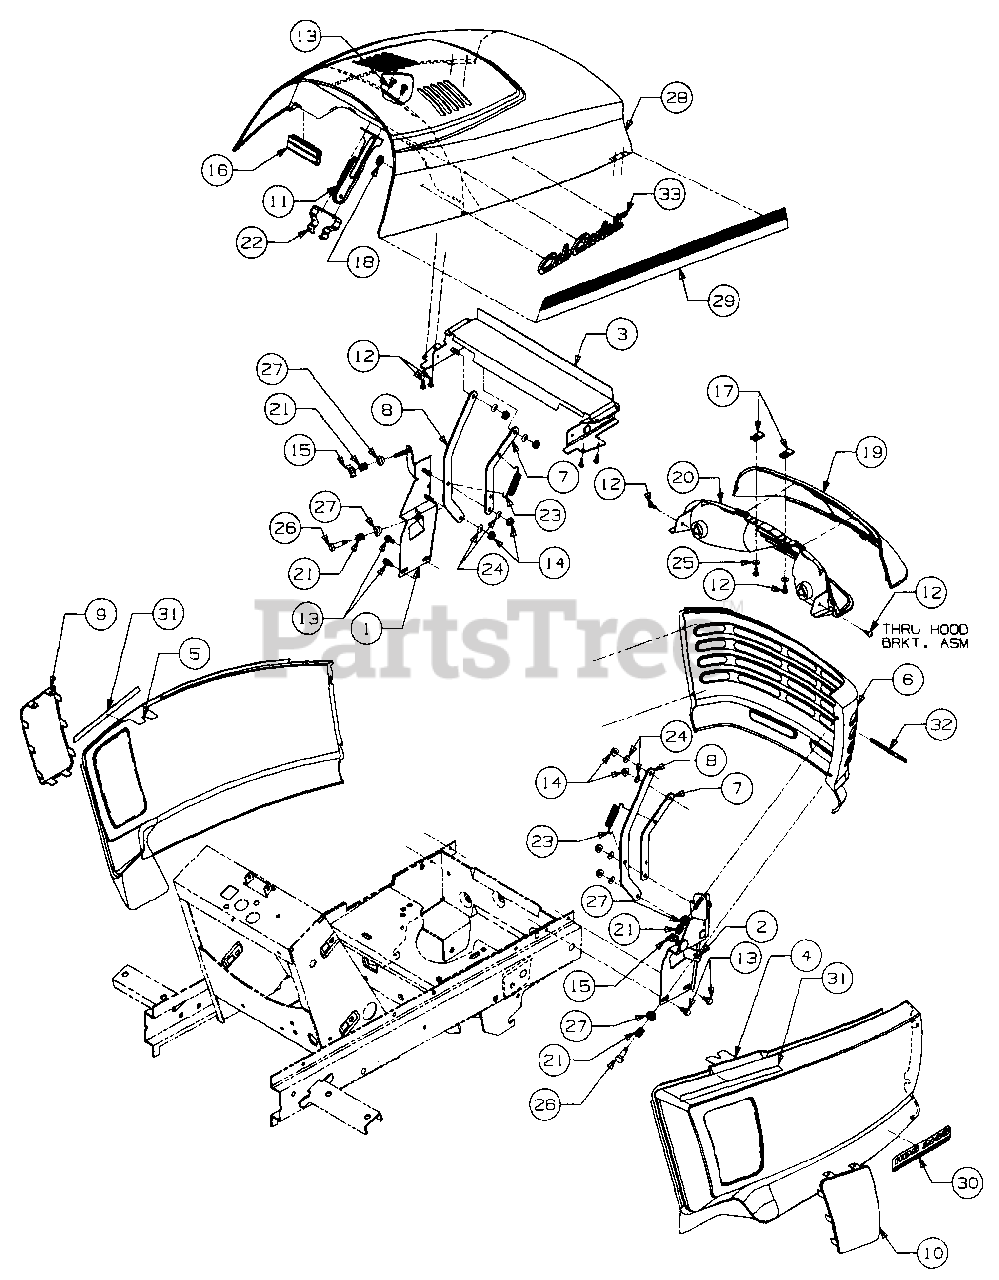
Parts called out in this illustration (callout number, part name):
1	Bracket, Grille LH
2	Bracket, Grille RH
8	Link, Long Hood
12	Screw, Truss Mach Tapp, #10 x .50 Lg
13	Screw, Hex Wash Tapp, 1/4 X .50 Lg
14	Nut, Hex Flange Lock, 1/4-20
15	Nut, Wing, 1/4-20
16	Seal, Heat Baffle
17	Nut, U-Type Speed, #10
18	Retainer, Push Nut
19	Lens, Cub Cadet
20	Reflector, Headlight
21	Spring, Compression, .50 OD X .50 Lg
22	Spring, Hood Latch
23	Spring, Extension, .50 OD x 2.25 Lg
24	Washer, Spring, .265 x .562 x .025 Thk
25	Washer, Flat, .218 X .62 X .063 Thk
26	Bolt, Shoulder .31 Dia X .75 Lg
27	Bushing, Tapered
30	Graphic, HDS 2135
31	Strip, Protective
32	Graphic, Warning Hot
33	Script w/Studs, Cub Cadet
